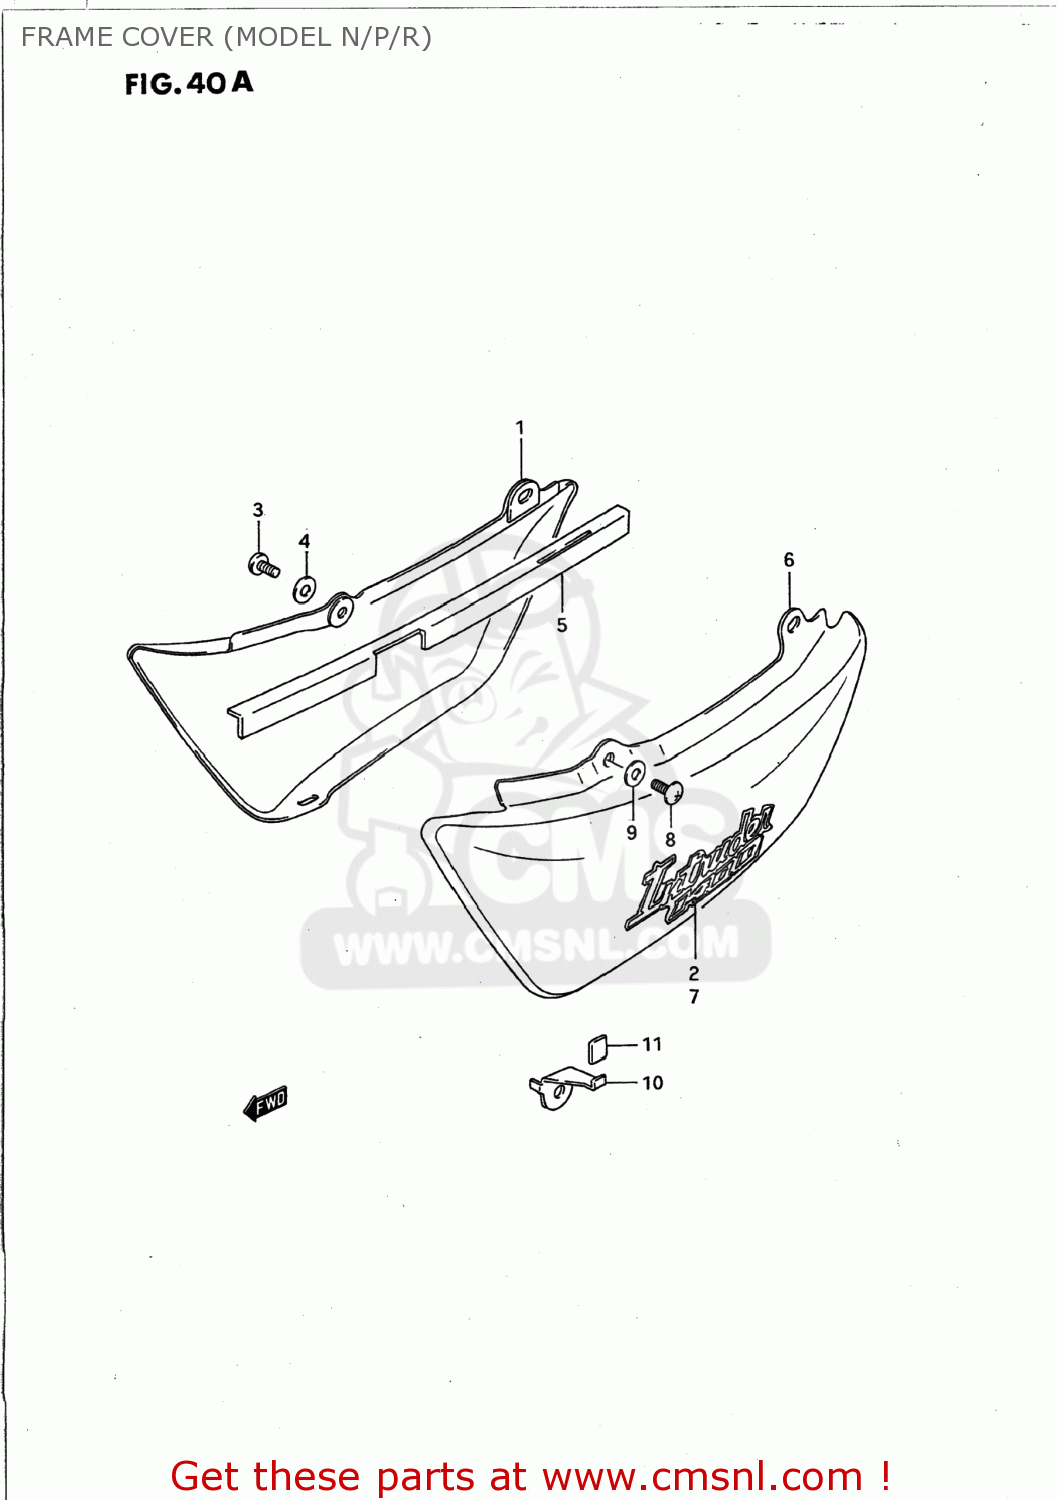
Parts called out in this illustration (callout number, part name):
1	COVER ASSEMBLY,FRAME,RIGHT
2	EMBLEM,FRAME COVER
3	SCREW 6X12
4	WASHER(6.5X18X1.6)
5	PROTECTOR,FRAME COVER,R
6	COVER ASSEMBLY,FRAME,LEFT
7	EMBLEM,FRAME COVER
8	SCREW 6X12
9	WASHER(6.5X18X1.6)
10	HOOK,FRAME COVER,L
11	CUSHION,FRAME COVER HOOK
